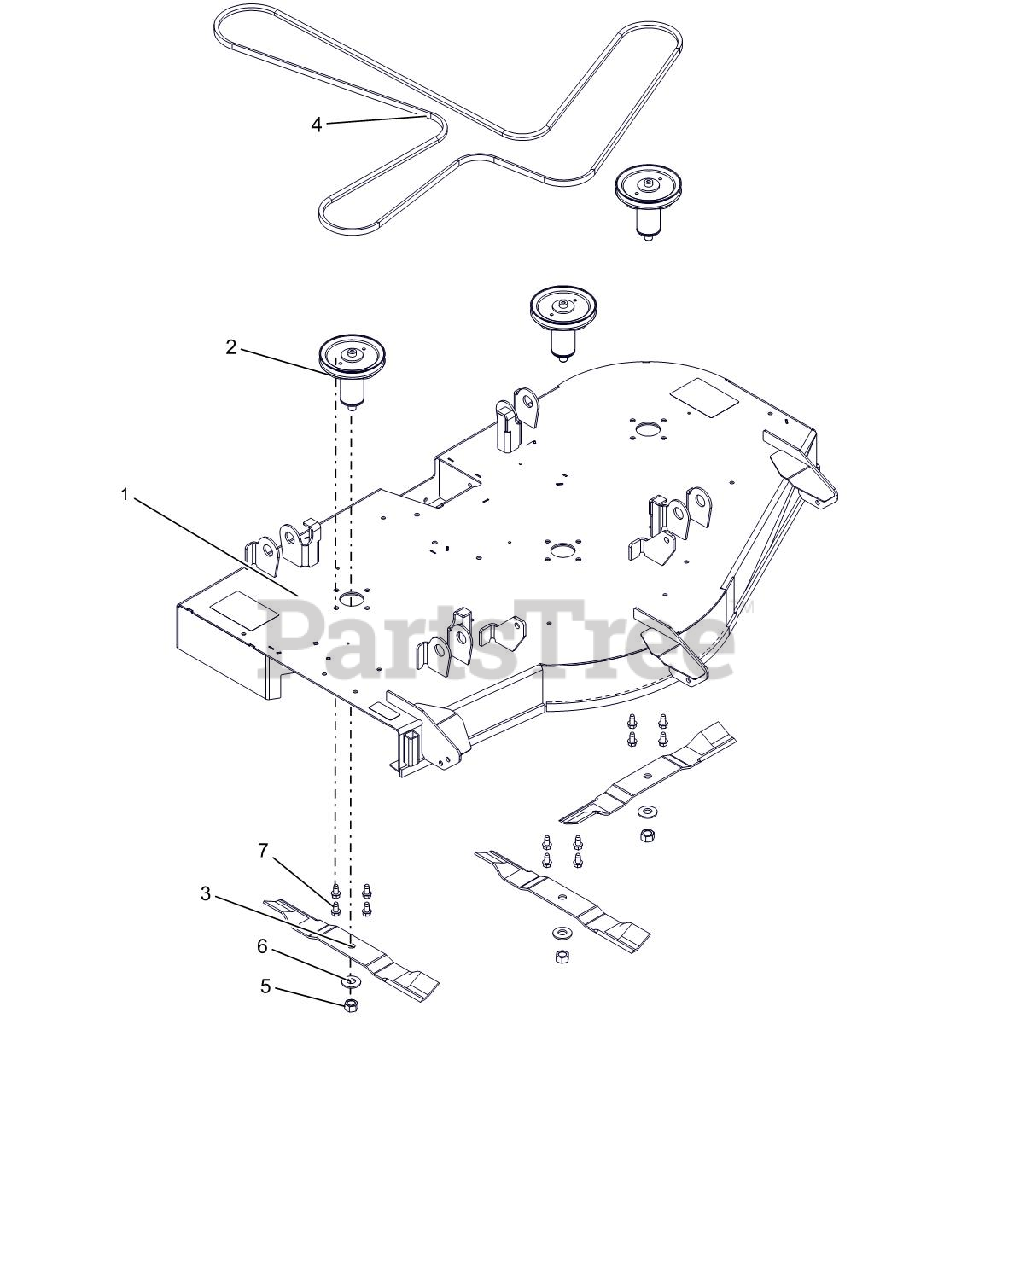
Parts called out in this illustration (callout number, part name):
1	KIT, 52" ARIENS DECK W/DECALS
2	KIT, DECK SPINDLE ASM-52
3	BLADE, 18" - 30 DEG .5 OFFSET
4	V-BELT, HA-WRAPPED
5	NUT-HEX .62-18 YWZC
6	WSHR-BLVL .669X1.535X.138
7	@SCR-TAP .38-16X.75 HWH TR YWZ
